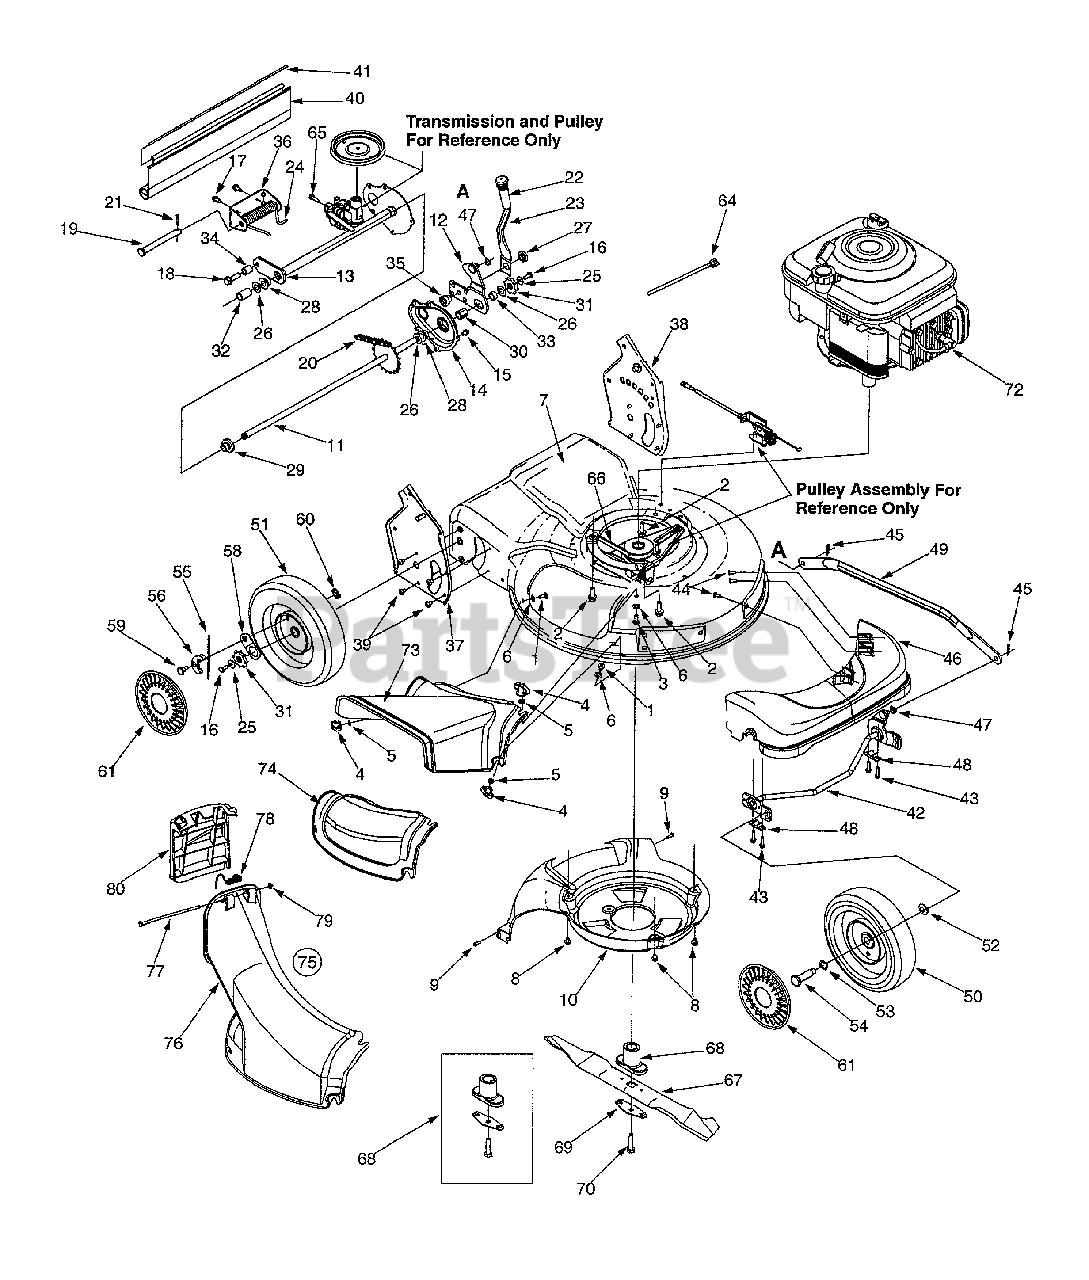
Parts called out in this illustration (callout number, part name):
1	Carriage Screw 1/4-20 x .62
2	Scr. TT:3/8-18:1.00
3	Scr. 1/4-20 x .750
4	Wing Nut 1/4-20
5	Nut, Push .25 I.D. x .50 O.D.
6	Wash. Fl. .334 I.D.x.62 x.03
8	Scr. TT. 1/4-20 x .375
9	Scr. HL. 1/2-14 x .750
10	Baffle
11	Rear Axle Ass'y
16	Cap Screw HH 1/4-20 x .620
17	Scr. AB 1 /4-14 x .625
18	Scr. 3/8 116 x .25
19	Clevis Pin .50 Dia. x 4.82 Lg.
20	Chain-Endls. #48 .500P x 24L
21	Cotter Pin .125 O.D. x .75
23	Spring Lever
24	Torsion Spring
25	Bell Wash. .285 x .75 x .082
26	Fl. Wash .508 I.D. 1.000 x.020
27	Nut Shld. .825 Dia. x .165 Lg.
28	Hx Flg. Brg .506 I.D. x .590 L.
29	Hx.Flg. Brg. .506 I.D. x.715 L.
30	Hx. Slv. Brg .504 I.D. x .830 L.
31	Wheel Rachet
32	Spa. .550 I.D. x /750 O.D.
33	Spa. .51 .D. x .70 O.D. x 38 L.
34	Spa. .385 x .624 x .700
35	Shld. Spa. .385 I.D. X .715 Lg.
40	Trail Shield
41	Trail Shield Wire
43	Hx Scr. Wash Hd. Hi.-Lo.
44	Scr. Torx, Truss Hi.-Lo.
45	Cotter Pin .072 x 1.12 Lg.
46	Fr. Axle Cover, Yellow
47	Bowed Washer
48	Bush. Block .505 Dia. x .62
50	Wheel 8 x 2 Link, Yellow
51	Wheel 9 x 2 Link Yellow, Slv.
52	Spr. Wash. .401 x .870 x .063
53	Wave Wash .510 x .750 x .017
54	Shldr Scr .498 x 1.445 x3/8-16
55	Spring, Ratchet, Plastic
56	Pawl - R.H.
56	Pawl - L.H.
58	Ratchet Pawl Plate
59	Scr. Shld. .340 x .285
60	Top Lock Tab Weld Nut 1/4-20
61	Hubcap -Yellow
64	Cable Tie
65	Hex Scr. 5/16-18
66	V-Belt
67	21" Mulching Blade
68	Blade Adapter Kit
69	Blade Bell Suport
70	Hex Bolt 3/8-24 x 2.5"Lg.
72	Spark Plug Insulator
73	Side Discharge Chute
74	Mulch Cover
75	Rear Chute Ass'y w/ Door
76	Discharge Chute
77	Pivot Rod
78	Torsion Spring
79	Push Cap
80	Chute Door
